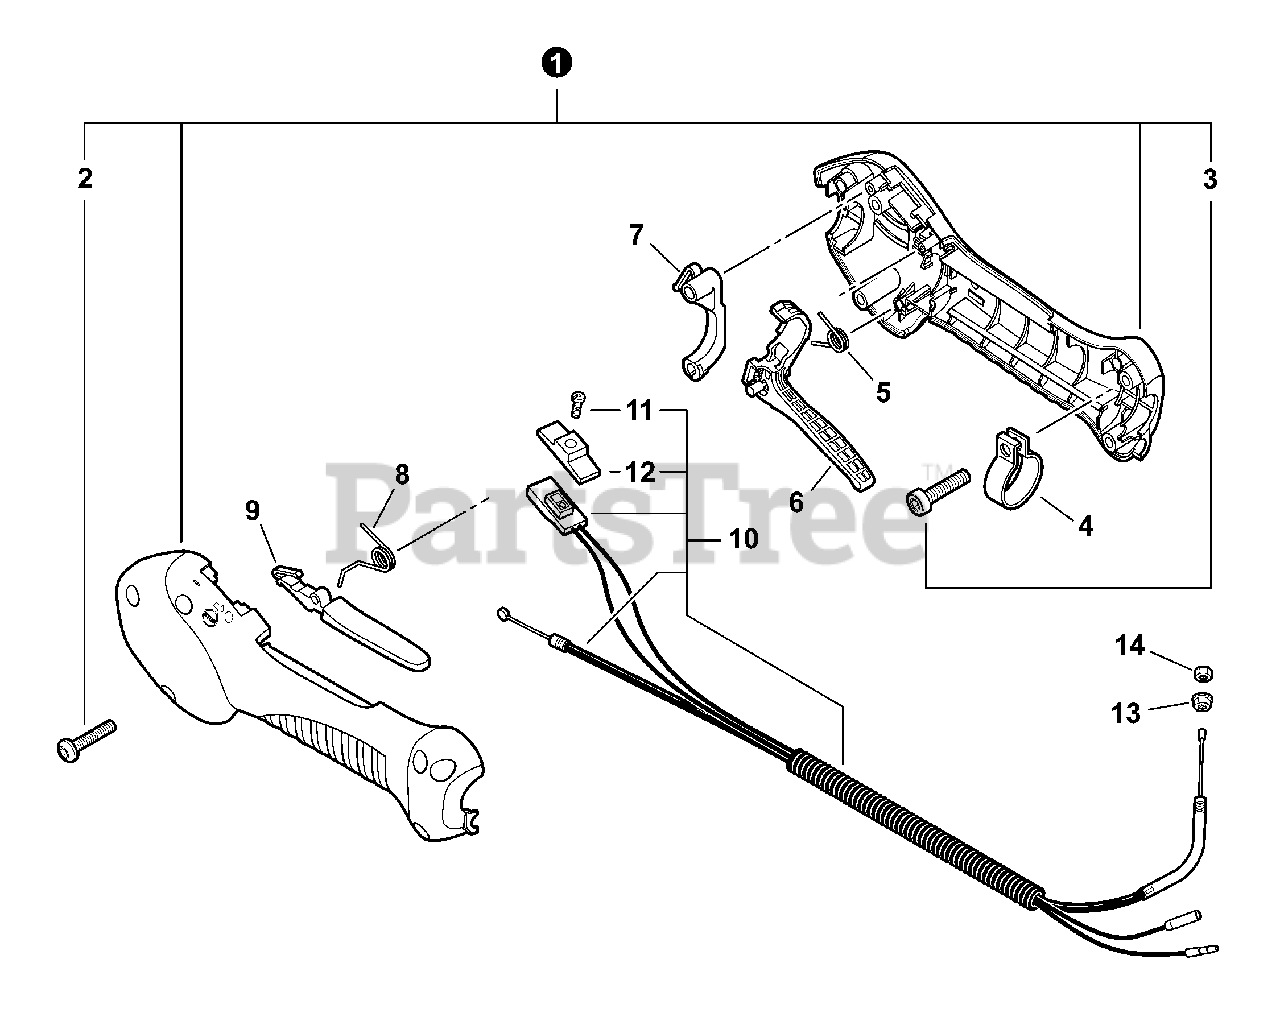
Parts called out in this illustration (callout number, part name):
1	CONTROL HANDLE KIT
2	BOLT, TORX 4×20
3	BOLT, TORX 5×20
5	SPRING, TORSION
6	TRIGGER, THROTTLE
7	LOCKOUT, THROTTLE
8	SPRING, TORSION
9	LEVER, THROTTLE LOCKOUT
10	CABLE ASSY, CONTROL
11	SCREW 3×10
12	KNOB, SWITCH - ORANGE
13	NUT, FLANGE M6
